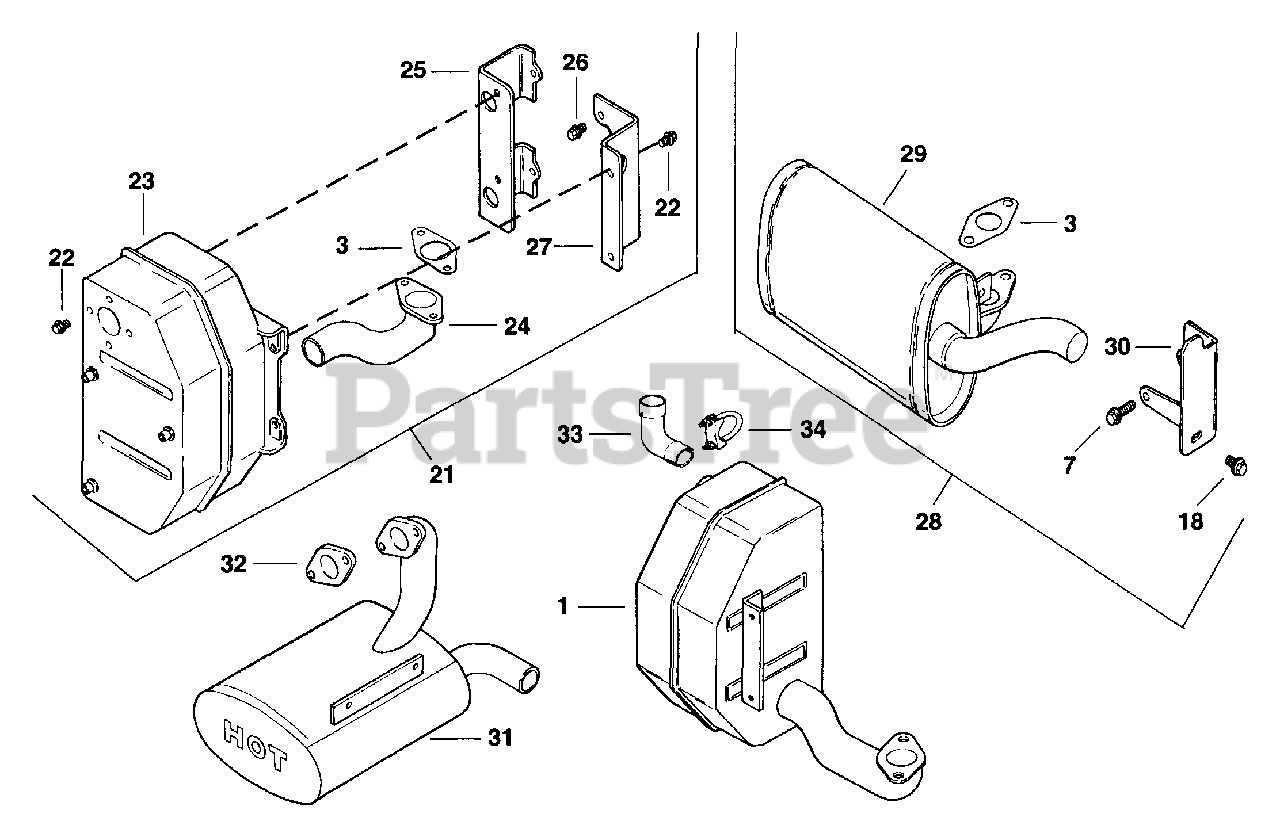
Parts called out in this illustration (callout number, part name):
3	GASKET, EXHAUST MANIFOLD
7	SCREW - USE M-645025
33	ELBOW, EXHAUST
